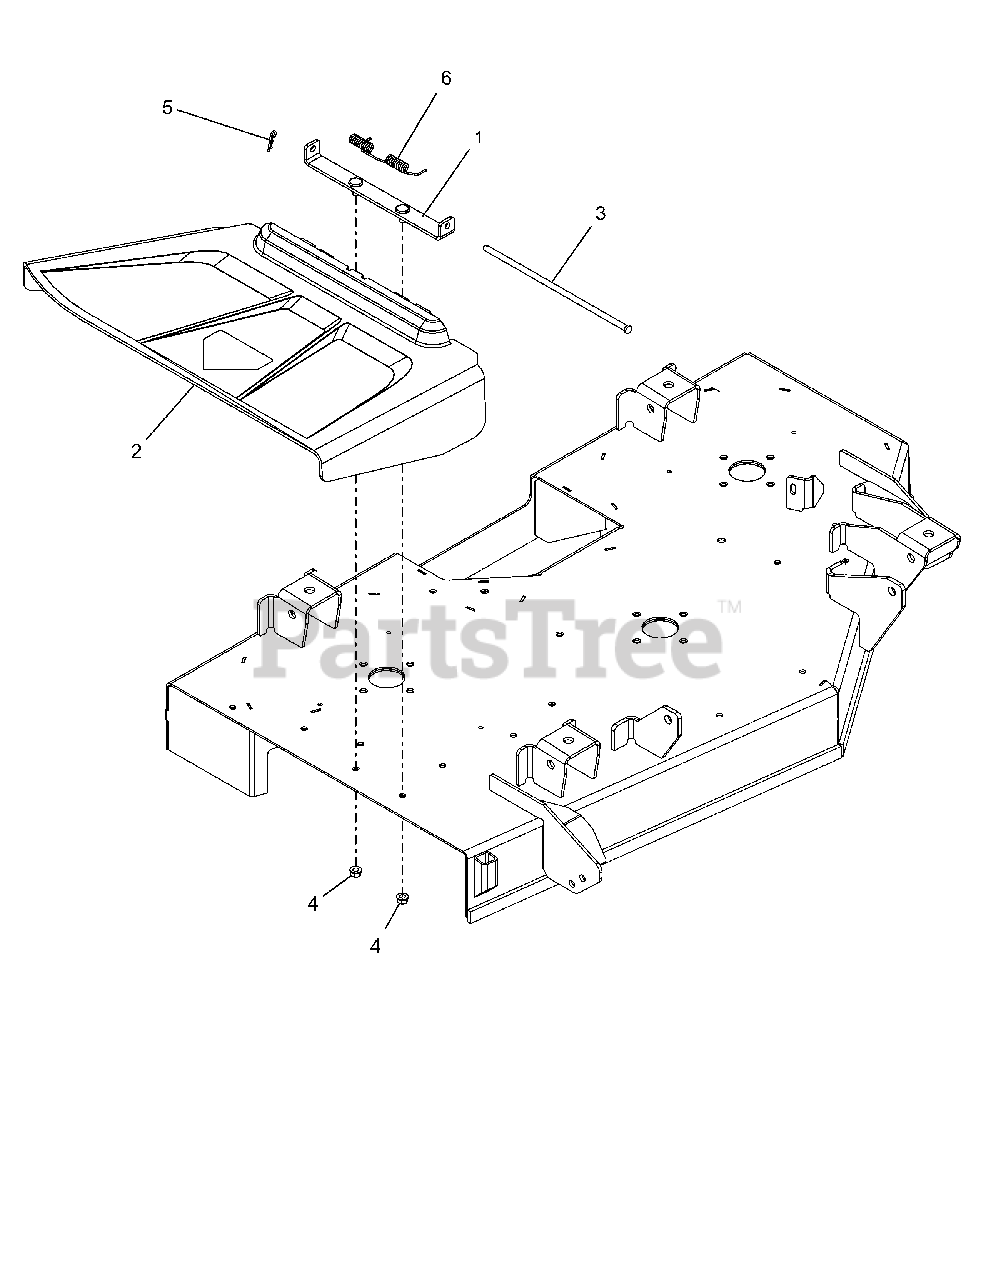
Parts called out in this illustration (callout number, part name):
1	WLDMT, CHUTE MT BRKT
2	CHUTE, SIDE DISCHARGE
3	PIN, 5/16 X 10.5
4	NUT-LK-TOP-FLG .312-18 GF ZCC
5	PIN, HAIR #213 .08X1.19 ZCC
6	SPRING-TORSION
